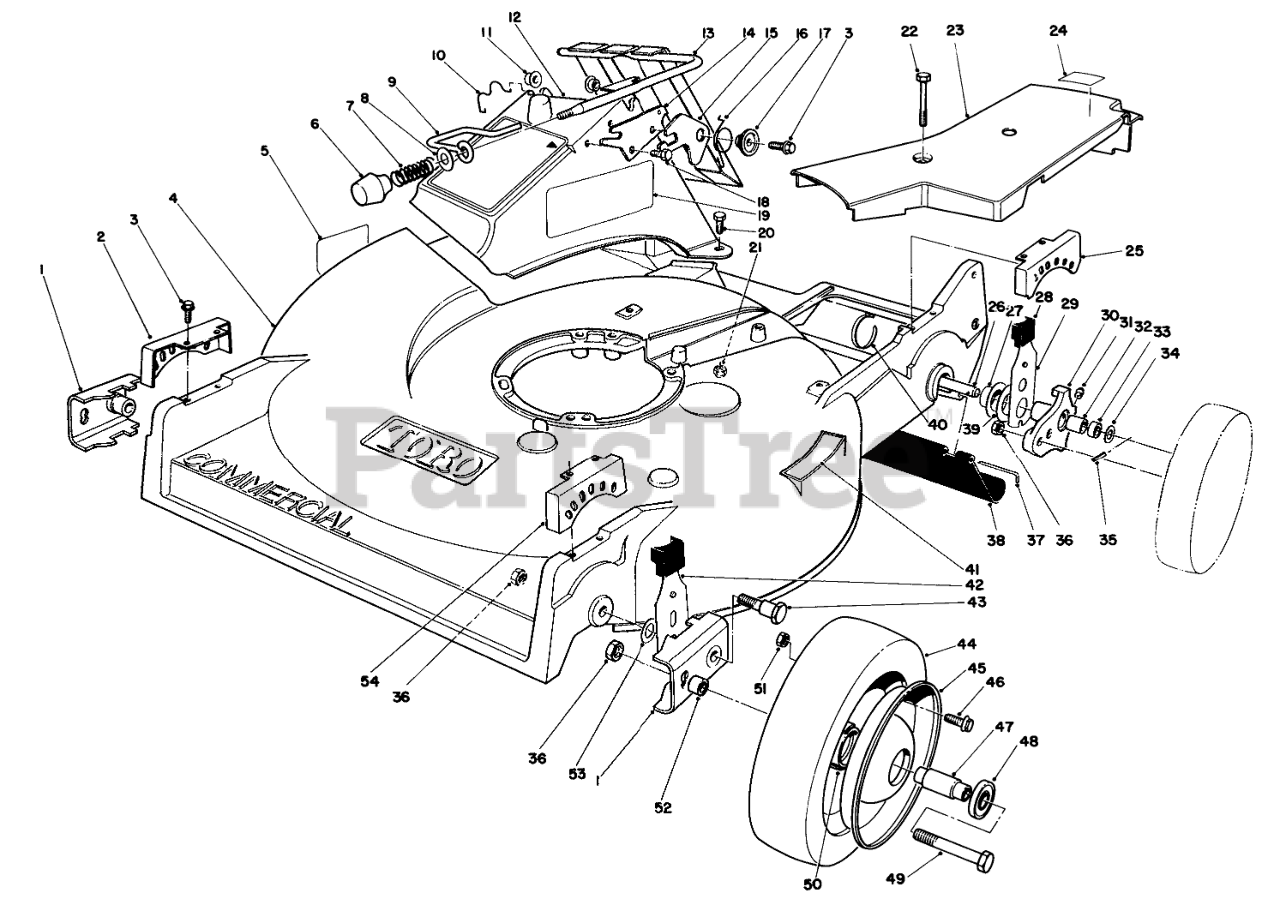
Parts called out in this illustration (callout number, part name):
1	PIVOT ARM
2	QUADRANT-FRONT, RH
3	Screw
4	Housing-Commercial (Incl. Ref. #5, 41)
5	DECAL-DANGER
7	COMPRESSION SPRING
8	WASHER-FLAT
9	DOOR LATCH
10	DOOR RETAINER
11	BUSHING-NYLON
12	Chute & Door Assy. (Incl. Ref. #3, 6-11 & 13-21)
13	DOOR & HANDLE WA
14	DOOR LATCH PLATE
15	SAFETY LATCH
16	TORSION SPRING
17	DOOR SPACER
18	SCREW-HWH
19	DECAL SAF INST
20	SCREW-HH
21	NUT-LOCK, NI
22	SCREW-HHFTF
23	Belt-Cover
24	LABEL-GREASE, HP
25	QUADRANT-REAR, LH
26	SHAFT-AXLE, REAR
27	CAP-END
28	KNOB-ARM
29	Spring Arm
30	Pivot Arm (Incl Ref. #31-33)
31	FITTING-GREASE
32	BUSHING
33	BUSHING
34	WASHER-PLAIN
35	PIN-SPIROL
36	NUT-LOCK, NI
37	ROD-SHIELD
38	SHIELD-TRAILING
39	WASHER
40	TIE-CABLE
41	STEP PAD DECAL
42	SPRING ARM ASM-FRONT
43	PIVOT SCREW
45	Wheel-Half
46	SCREW-HHF
47	SPACER-BEARING
48	BEARING-WHEEL
49	SCREW-HH
50	HUB-BEARING
51	NUT-LOCK, NI
52	SPACER-WHEEL
53	WASHER-PIVOT
54	QUADRANT-FRONT, LH
